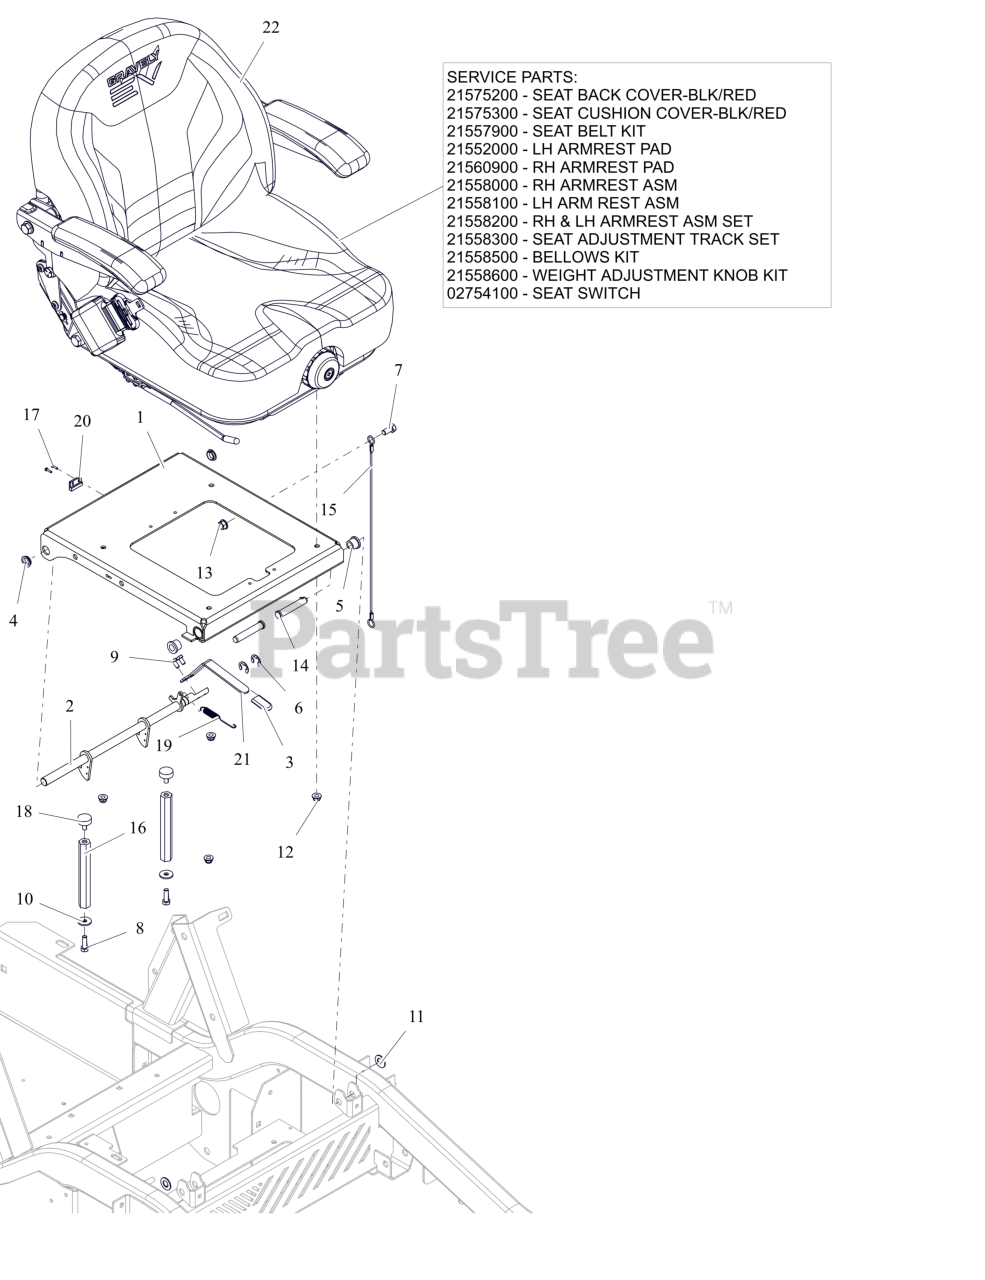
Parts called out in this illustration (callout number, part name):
1	WLDMT, SEAT PLATE (RED)
2	WLDMT, SEAT LATCH (RED)
3	GRIP, SEAT LEVER, GREY
4	BUSHING, POLYLINER-.63 SNAPIN
5	BSHG, FLG .516X.750X.625X.937
6	RG-RTNG-EXT .625X.042
7	BLT,HEX .38-16X.75 G5 ZCC
8	BLT, HEX .31-18X1.00 G8 ZCC M
9	BLT, HEX 0.375-16X1 GR5 EP80 ZC120
10	WSHR,FLT .328X1.00X.094 ZCC
11	WSHR, FLT .531X1.00X.063 ZCC
12	NUT,NYL-FLG .31-18 GF ZCC
13	NUT-LK-CTR-FLG .375-16 GF ZCC
14	PIN, SLIC-.500X42.70X2.31 -ZC
15	CABLE, WIRE (LANYARD)-.093X16.20
16	NUT, COUPLING .312-18 X 5.715
17	SCR-TAP #4-40X.50 HWH ZCC
18	BUMPER, RUBBER
19	SG-TENS .043X.44X3.31 WLD 5.8
20	SWITCH, MAGNET (NO WIRE)
21	LEVER, LATCH SEAT (RED)
22	SEAT, GRAVELY MECH SUSPENSION LVR
22	SEAT BACK COVER-BLK/RED
22	SEAT CUSHION COVER-BLK/RED
22	KIT, SEAT BELT
22	PAD, ARMREST
22	PAD, ARMREST (HARD)
22	ARMREST, RH ASSEMBLY
22	ARMREST, LH ASSEMBLY
22	SET, RH & LH ARMREST ASSEMBLY
22	SET, SEAT ADJUSTMENT TRACK
22	KIT, BELLOWS
22	KIT, WEIGHT ADJUSTMENT KNOB
22	SWITCH- SNAP MTG N.O.
